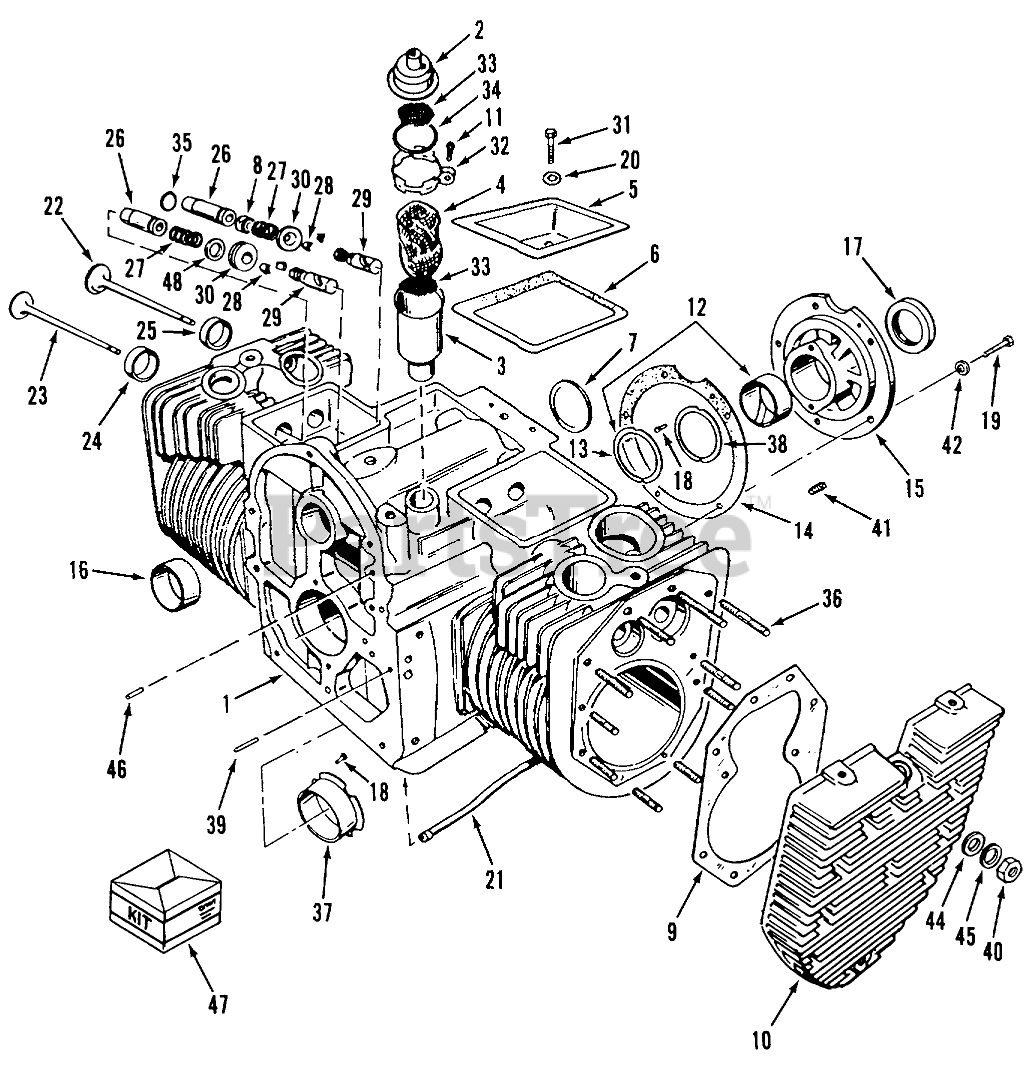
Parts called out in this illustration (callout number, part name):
1	Short Block 24HP
2	Breather Cap & Valve
3	Breather Tube
4	Baffle
5	VALVE COMPARTMENT
6	Valve Cover Gasket
7	Plug
8	Intake Valve Seal
9	Cylinder Head Gasket
10	Cylinder Head
11	Screw #8 x 3/4
12	Rear Crankshaft Bearing-STD
13	ThrustWasher
14	Gasket
15	Bearing Plate
16	Camshaft Brg
17	Oil Seal
18	Screw
19	SPRING LOCKWASHER
20	Washer
21	Crankcase Oil Tube
22	INTAKE VALVE
23	EXHAUST VALVE
24	Exhaust Seat Insert-Std
25	Intake Seat Insert-STD
26	Exhaust Valve Guide
27	Spring-Valve
28	Valve Spring Lock
29	Tappet
30	Rotator-Valve
31	Bolt 1/4-20 x 2
32	Clamp
33	Screen
34	Seal
35	Intake Valve Guide Gasket
36	Mtg. Stud-Cylinder Hd (Install 4 Bottom Holes LH, RH Hd)
37	Standard
38	Shim 0.005"
39	Pin
40	Nut
41	Screw
42	Lockwasher 3/8
44	Washer
45	O-Ring
46	Plug
47	Gasket Kit-Carbon Removal
48	Washer
